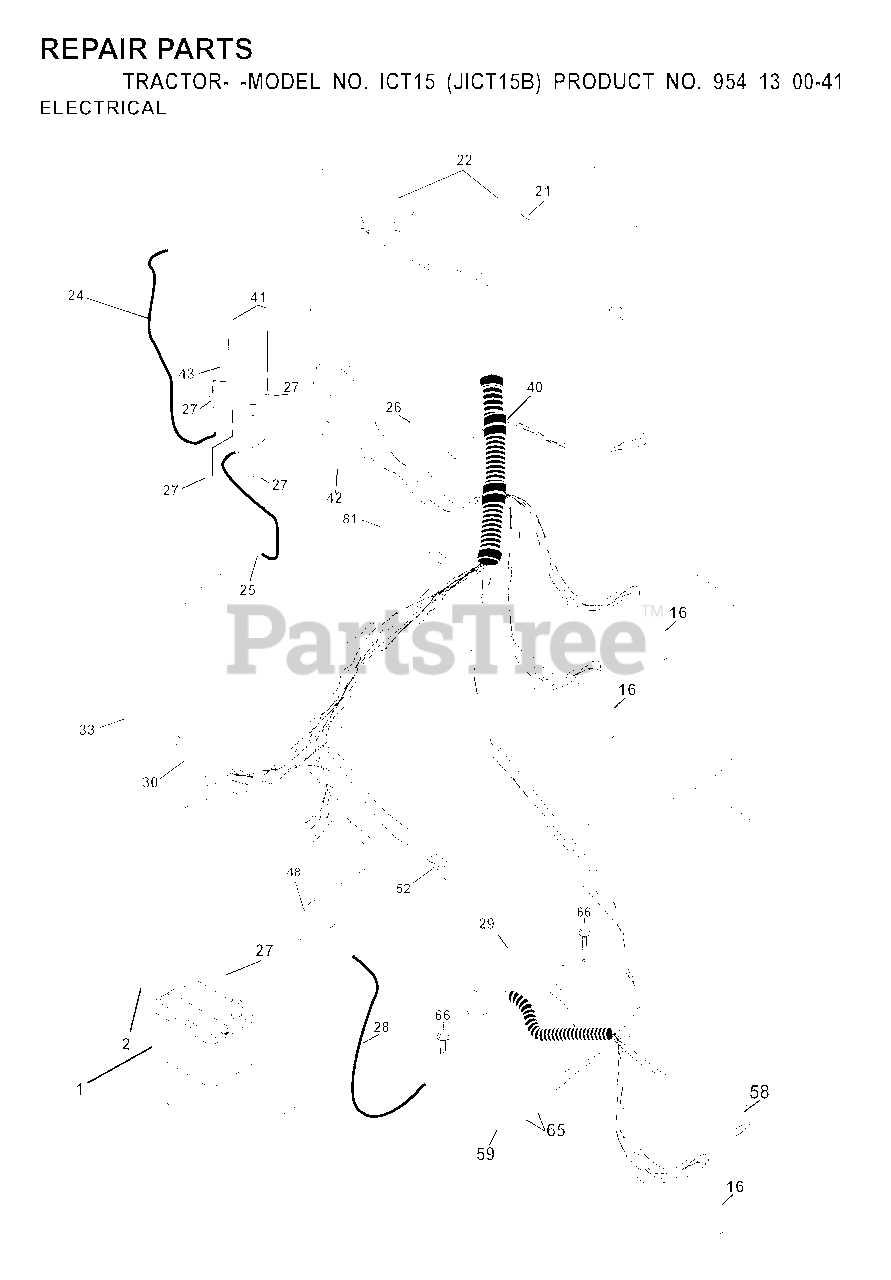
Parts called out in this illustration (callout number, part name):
1	BATTERY 12 VOLT 25 AMP
16	SWITCH INTERLOCK
21	HARNESS ASM, LIGHT W/4152J
22	LIGHTBULB
24	BATTERY CABLE GT
25	CABLE BATTERY
26	FUSE 15 AMP
27	NUT
28	CABLE GROUND
29	PLUNGER SWITCH (COLOR:OLIVE)
33	KEY MLD GEN DELTA
42	TERMINAL COVER
43	SOLINOID
52	WIRE PROTECTION LOOP
58	BUZZER
81	RELAY.ASSY.T
